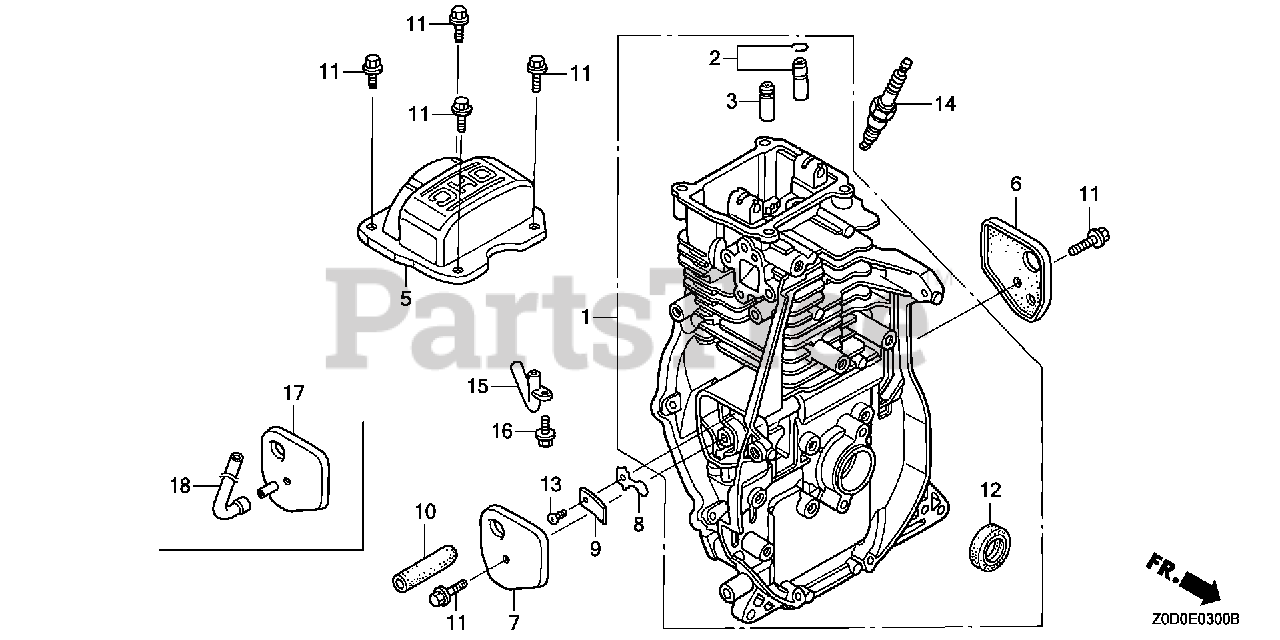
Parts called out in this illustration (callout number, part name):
1	CYLINDER ASSY.
2	GUIDE ASSY., EX. VALVE (OVER SIZE)
3	GUIDE, VALVE (OVER SIZE)
5	COVER, HEAD
6	COVER A, BREATHER
7	COVER B, BREATHER
8	VALVE, OIL OUTLET
9	PLATE, STOPPER
10	TUBE, BREATHER
11	BOLT, FLANGE (6X14) (CT200)
12	OIL SEAL (20X32X6)
13	SCREW, PAN (3X5)
14	SPARK PLUG (CR5HSB)
